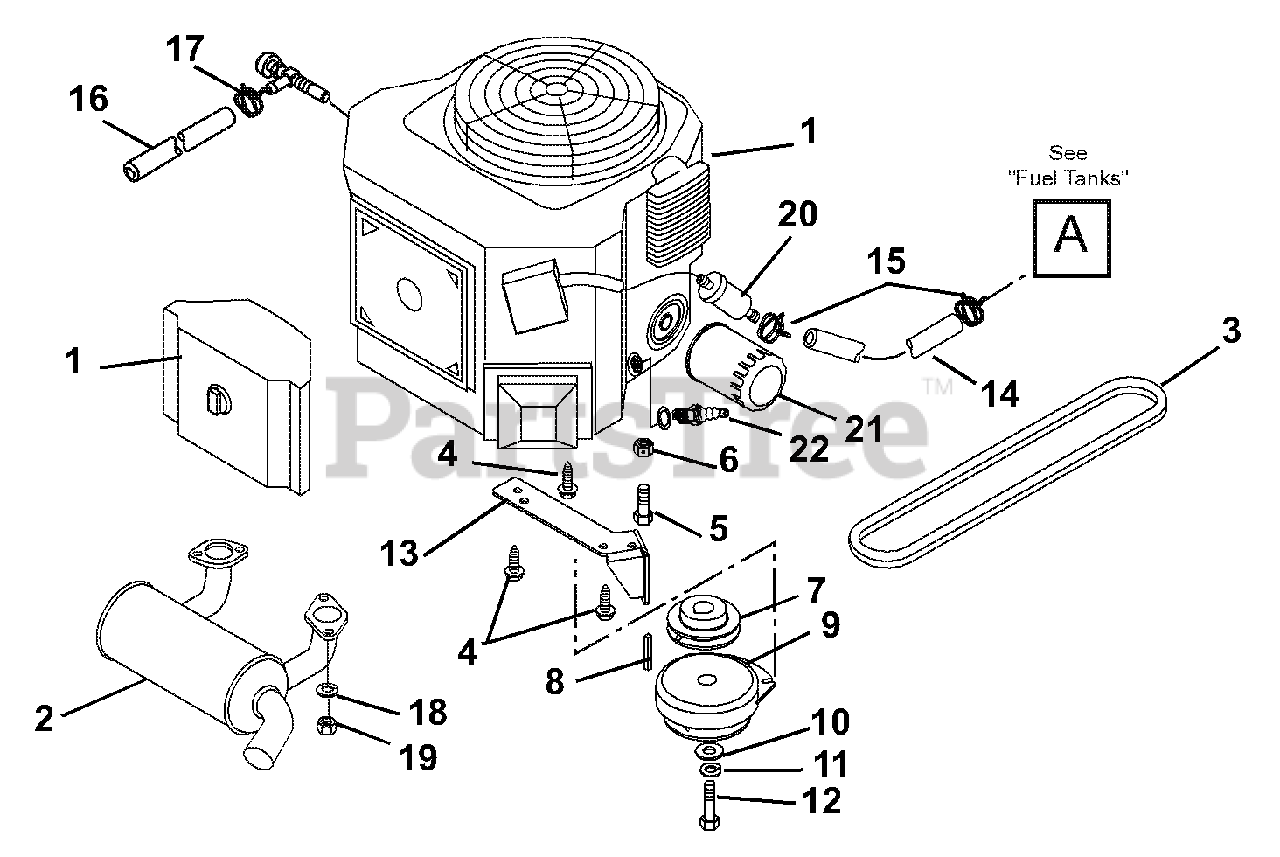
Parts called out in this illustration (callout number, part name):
1	ENGINE, 15HP KAW FH451V
2	MUFFLER, KAW. (COMPACT-Z)
3	V-BELT, HA-RAW EDGE
4	@SCR-TAP .38-16X1.00 HWH TR YZ
5	@BLT-HEX .31-18X1.50 GR5 YWZC
6	@NUT-LK-TOP-FLG .31-18 YWZC
7	PLY-V 4.OO X 1.00
8	KEY-SQ .25X.625X.25 SAE 8630
9	CLUTCH,ELECTRIC PTO
10	WSHR-FL-STL .469X2.00X.25 YWZC
11	@WSHR-LK .44X.109 REG YWZC
12	BLT-HEX .44-20X2.50 GR5 YWZC
13	STOP, CLUTCH
14	HOSE, 5.75"-1/4" ID GAS LINE
15	CLAMP-HOSE WIRE .490/.510X.116
16	HOSE, 1/2 X 6.00
17	CLAMP,.88 DIA. HOSE
18	@WSHR-LK .31X.078 REG YWZC
19	NUT-HEX M8-1.25 YWZC
20	FILTER, FUEL - KOH CV20
21	FILTER,OIL - KAW
22	PLUG, SPARK
